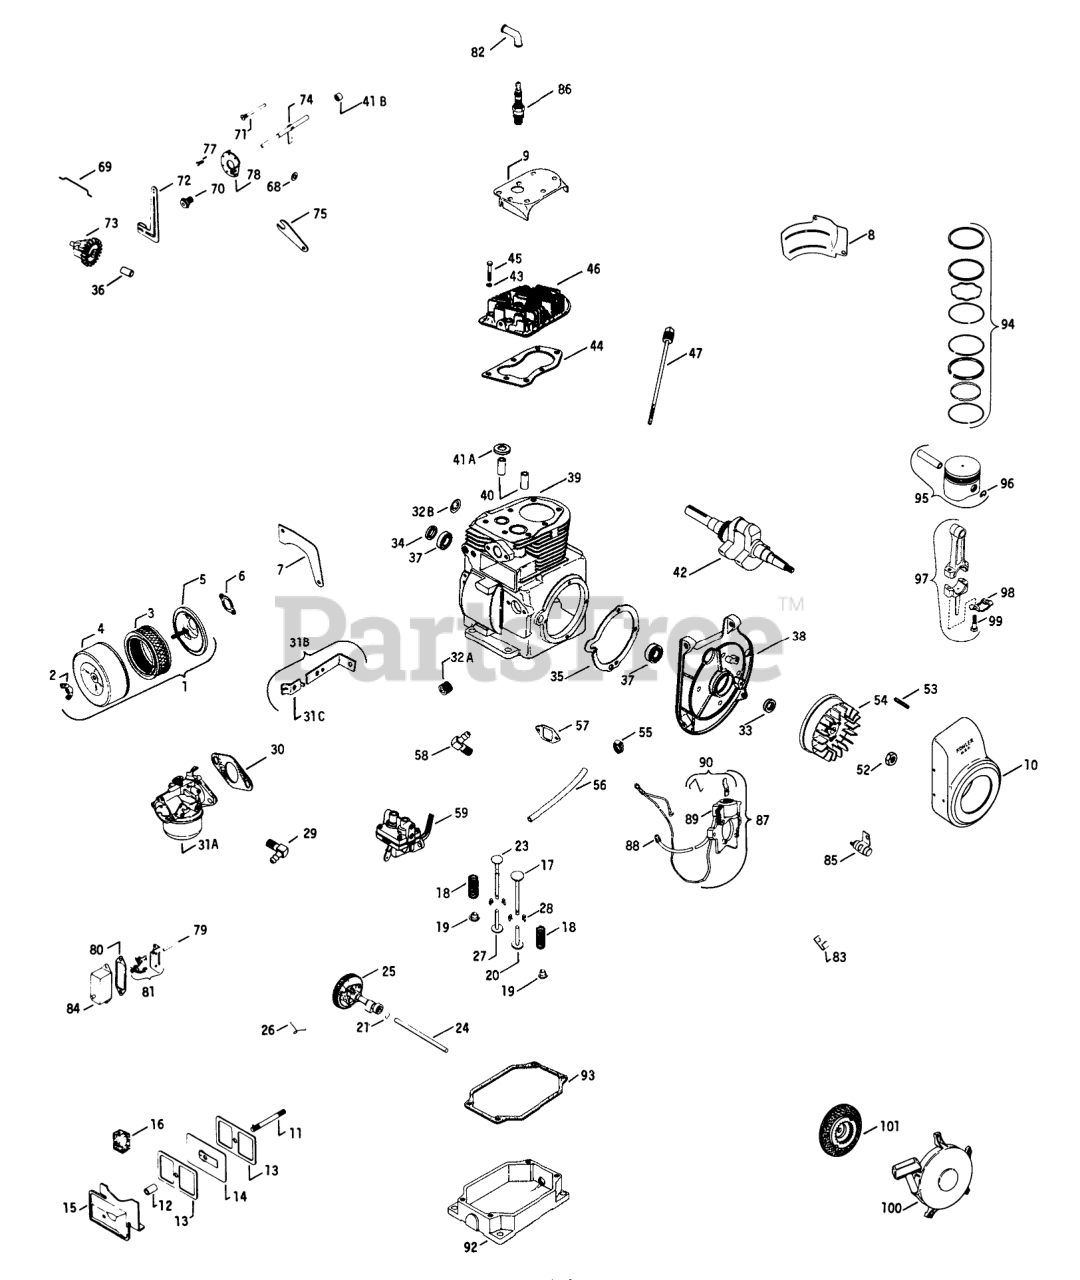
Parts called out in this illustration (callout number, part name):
1	Cleaner, air - assembly
2	Nut-Wing
3	Element, Air Cleaner
4	Cover, air cleaner
5	Base Air Cleaner
6	Gasket
7	Baffle side air
8	Baffle cylinder
9	Baffle, Head
10	Housing, blower
11	Stud valve cover
12	Seal
13	Gasket-Valve Cover
14	Breather
15	Cover, Valve
16	Filter
17	Valve-Intake
18	Spring, Valve
19	Retainer-Spring
20	Tappet, Valve
21	Spacer camshaft .005
21	Spacer, Camshaft.010
23	Valve, exhaust
24	Pin, Camshaft
25	Kit, camshaft
26	Spring-Actuating
27	Tappet-Exhaust Valve
28	Keeper, Valve
29	Elbow
30	Gasket-Carburetor
31A	Carburetor-Assembly
31B	Bracket, choke
31C	Clip
32A	Plug
32B	Plug
33	Seal Front Oil
34	Seal Rear Oil
35	Gasket
36	Pin-Dowel
37	Ball Bearing
38	Plate,Bearing
39	Block, cylinder - assembly (Use 8-234989 Miniblock)
40	Guide-Valve
41A	Insert
41B	Bearing
42	Crankshaft
43	Washer
44	Gasket, head
45	Screw, H.C. 5/16-18 x 1-1/2
46	Head, Cylinder
47	Dipstick
52	Nut
53	Key
54	Flywheel (Use 4102511 after serial no. 6366215)
55	Clamp
56	Line, Fuel
57	Gasket, pump
58	Elbow
59	Pump, fuel
68	Washer
69	Link-Governor
70	Bushing Governor
71	Pin-GovemorStop
72	Lever, Governor
73	Gear, Governor
74	Shaft-Governor Cross
75	Bracket, speed control
77	Pin
78	Disc, regulating
79	Rod, Breaker
80	Gasket, Cover
81	Breaker
82	Boot, Spark Plug
83	Clip
84	Cover breaker
85	Condenser
86	Spark plug
87	Stator
88	Cable, Hi-Tension
89	Kit, coil
90	Kit, Coil Clip
92	Pan, oil
93	Gasket, pan
94	Ring Set Std.
95	Piston - assembly (Std.) (Includes pin & retainers)
96	Retainer, Pin
97	Rod, Connecting Std.
98	Lock, Conn. Rod
99	90A9-5/66734 SENSAT
100	Starter, recoil-assem.
101	Cup, drive w/screen (Replaced by 41 071 02--41 071 02 must be used after serial no. 6366215)
